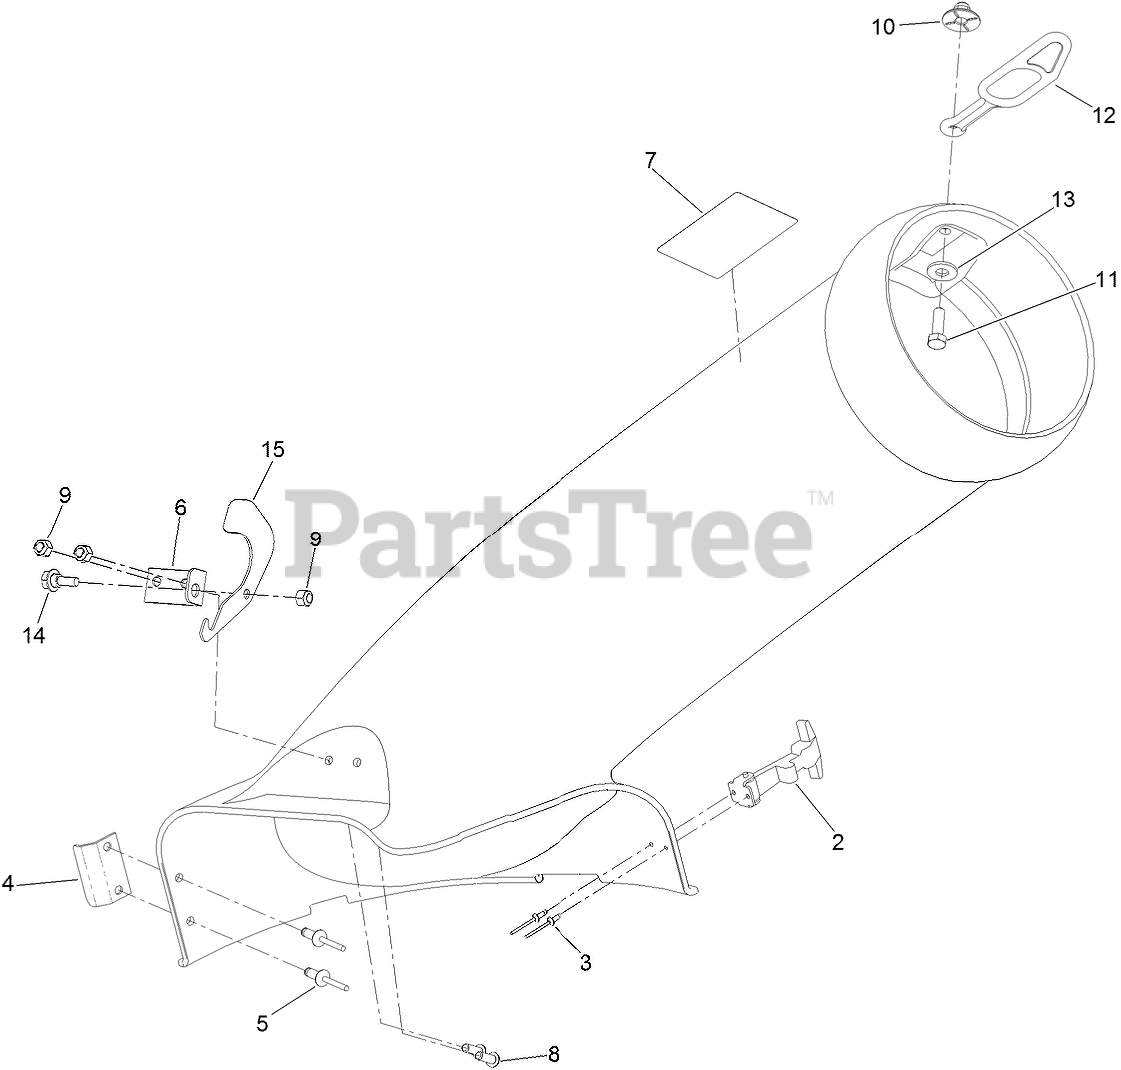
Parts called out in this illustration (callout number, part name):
2	HANDLE ASM
3	RIVET-POP
4	BRACKET-ELBOW
5	RIVET-BLIND
6	PLATE-PIVOT
7	DECAL-DANGER
8	SCREW-HSBH
9	NUT-LOCK, NI
10	NUT-IMPELLER
11	SCREW-HH
12	RETAINER-DUCT
13	WASHER-FLAT
14	SCREW-SHOULDER, HHF
